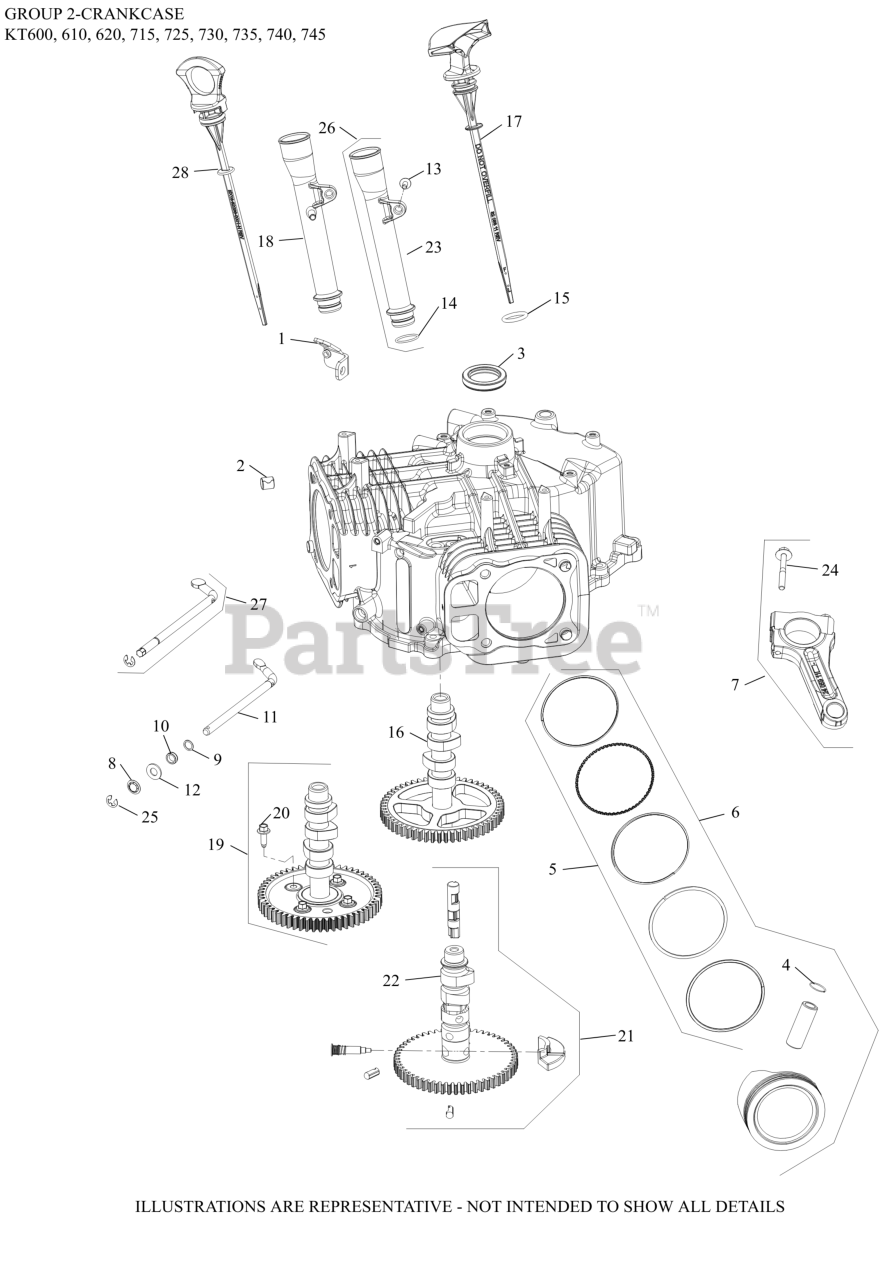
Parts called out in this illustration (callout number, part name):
1	BRACKET, OIL FILL TUBE
2	PIN, LOCATING
3	SEAL, OIL (HELIX LIP)
4	RETAINER, PISTON PIN
5	RING SET(STD)STYLE B-1.2mm Tp RING THICK
5	RING SET(.08)STYLE B-1.2mm RING THICK
5	RING SET(.25)STYLE B-1.2mm Tp RING THICK
5	RING SET(.50)STYLE B-1.2mm Tp RING THICK
6	KIT, PISTON 725CC (STD) STYLE B
6	KIT, PISTON 725CC (.08) STYLE B
6	KIT, PISTON 725CC (.25) STYLE B
6	KIT, PISTON 725CC (.50) STYLE B
7	ROD, ASSY CON (STD)-USE 24 067 30-S
7	ROD, ASSY CON(.25mm) -USE 24 067 31-S
9	WASHER, FLAT 11/32"
10	SEAL, GOVERNOR CROSS SHAFT
12	WASHER, FLAT 9 MM
16	CAMSHAFT ASSY
17	DIPSTICK, ASSY
18	TUBE ASSEMBLY, OIL FILL
24	KIT, ROD BOLTS-(#25086677S)
25	CLIP, RETAINER GOVERNOR SHAFT
27	KIT, CROSS SHAFT
NI	KIT, ROD BOLTS
